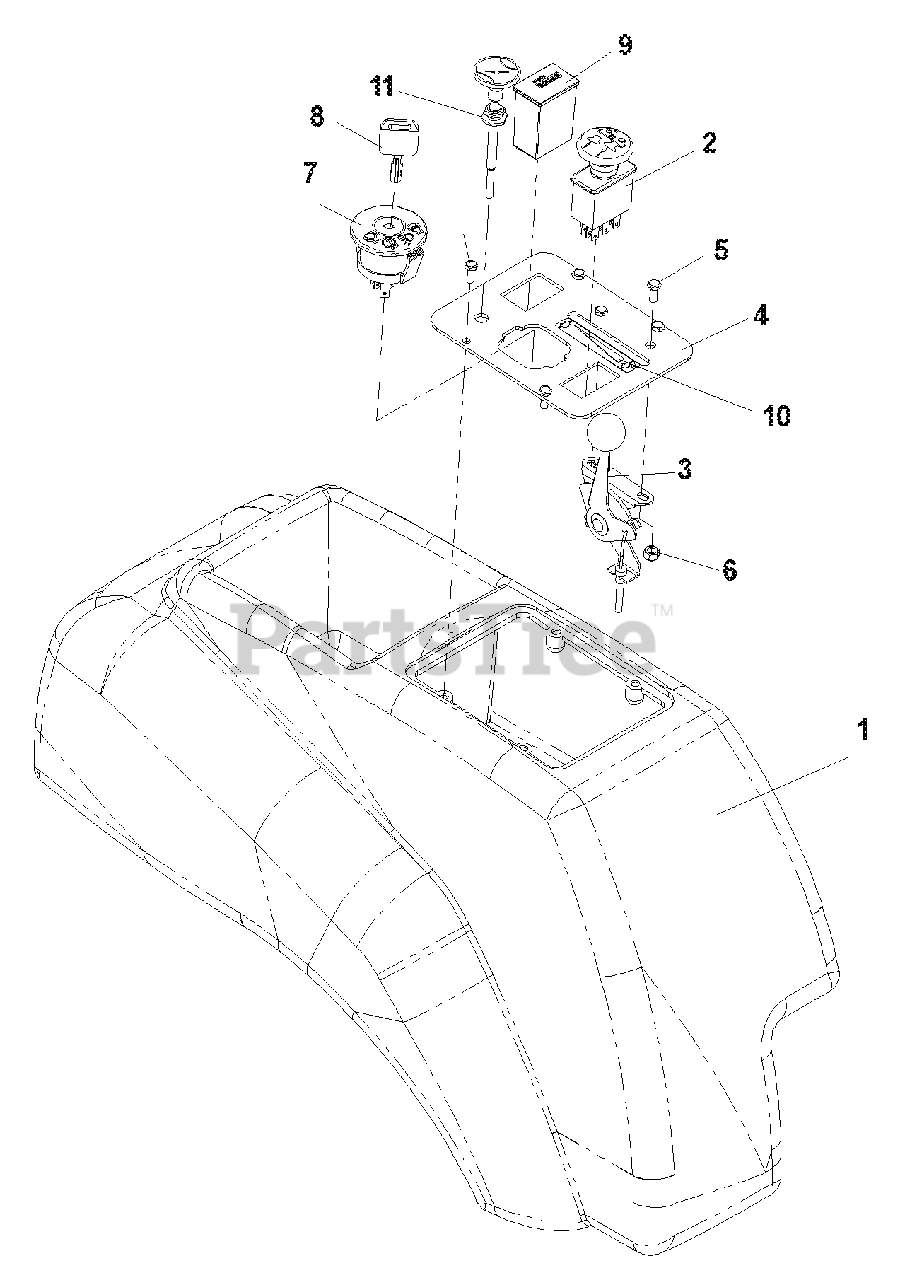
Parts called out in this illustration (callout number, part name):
2	CLUTCH SWITCH
3	THROTTLE CABLE
4	CONTROL CONSOLE
5	SCREW #10-24 X 1/2
6	NUT #10-24, NYLOC
7	IGNITION SWITCH
8	KEY
9	HOUR METER
10	DECAL, THROTTLE
11	CHOKE CABLE
